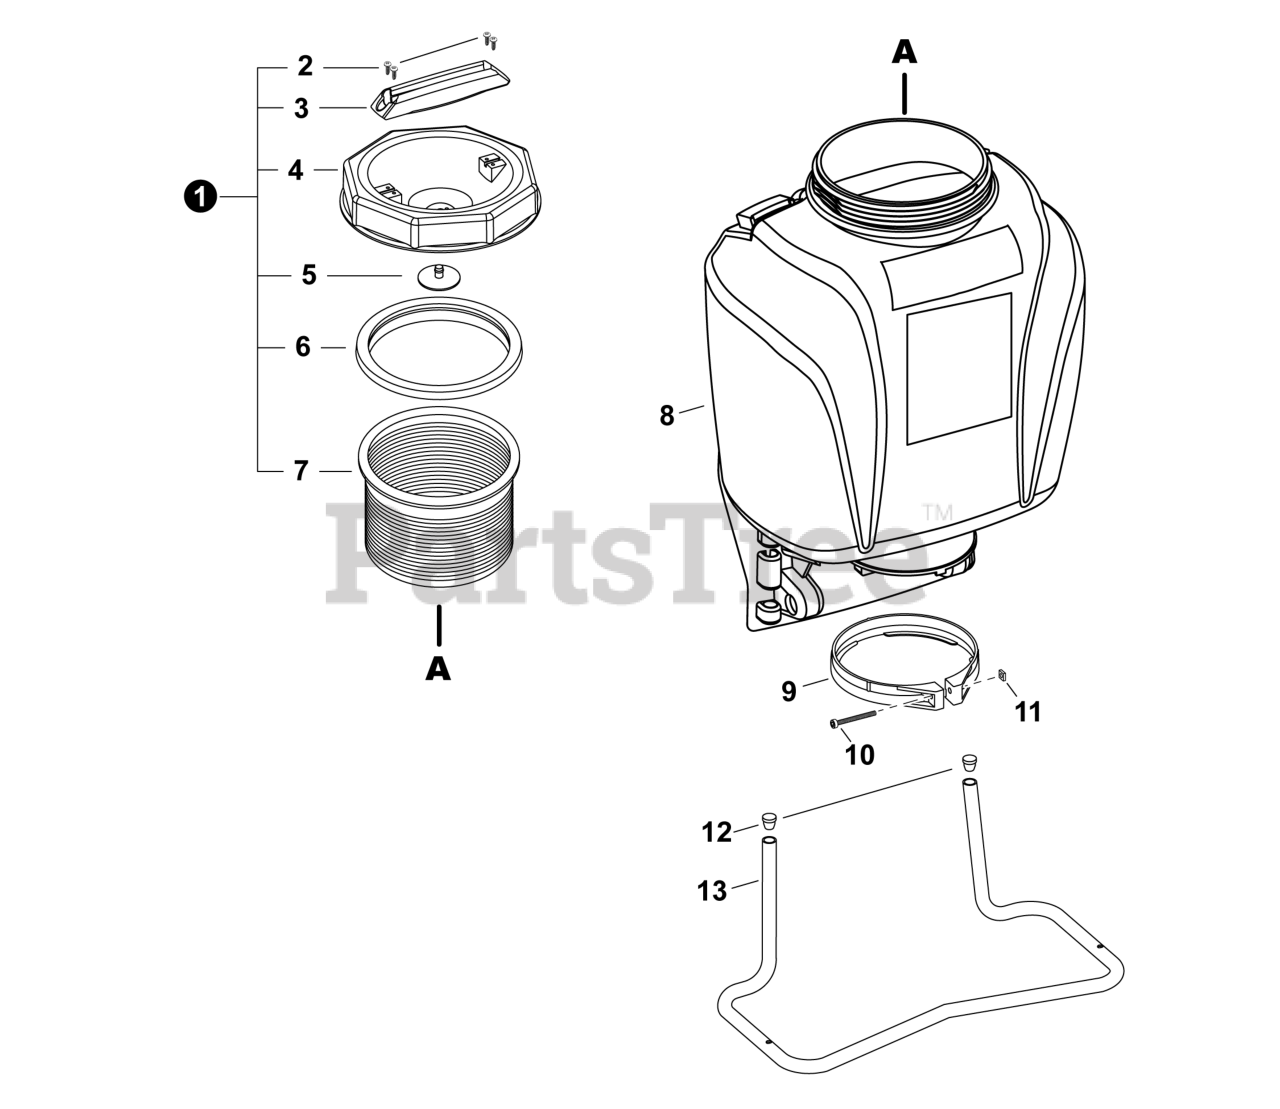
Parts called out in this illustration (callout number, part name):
1	CAP KIT, TANK
2	SCREW
3	HANDLE
4	CAP, TANK
5	VALVE, CHECK - CAP
6	GASKET, BASKET
7	BASKET, FILTER
8	BASE, PRESSURE CHAMBER
9	CLAMP, PUMP
10	SCREW, CLAMP
12	BASE, PRESSURE CHAMBER
13	BASE, PRESSURE CHAMBER
